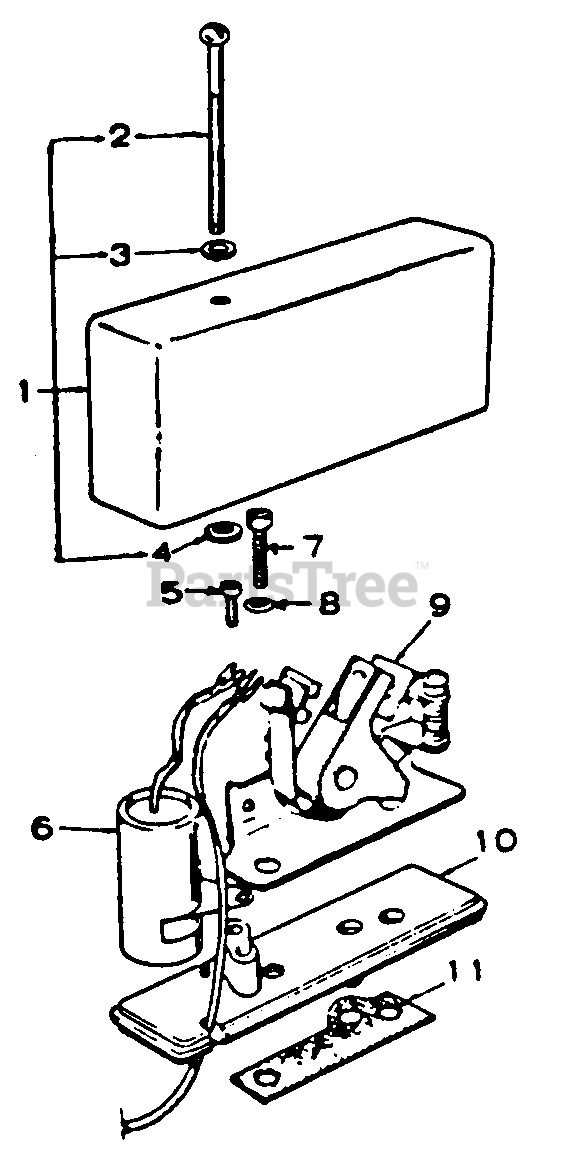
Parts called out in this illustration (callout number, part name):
2	Screw, No. 10 X 1-1/2 Pln R/Hds Mach
3	Washer, Cover Mtg
4	Retainer, O-Ring
5	Screw, Tapping
7	Screw, 1/4 X 3/4 H/Shd Cap
8	Washer, 1/4 Lock
9	Point Assy, Breaker
11	Gasket
